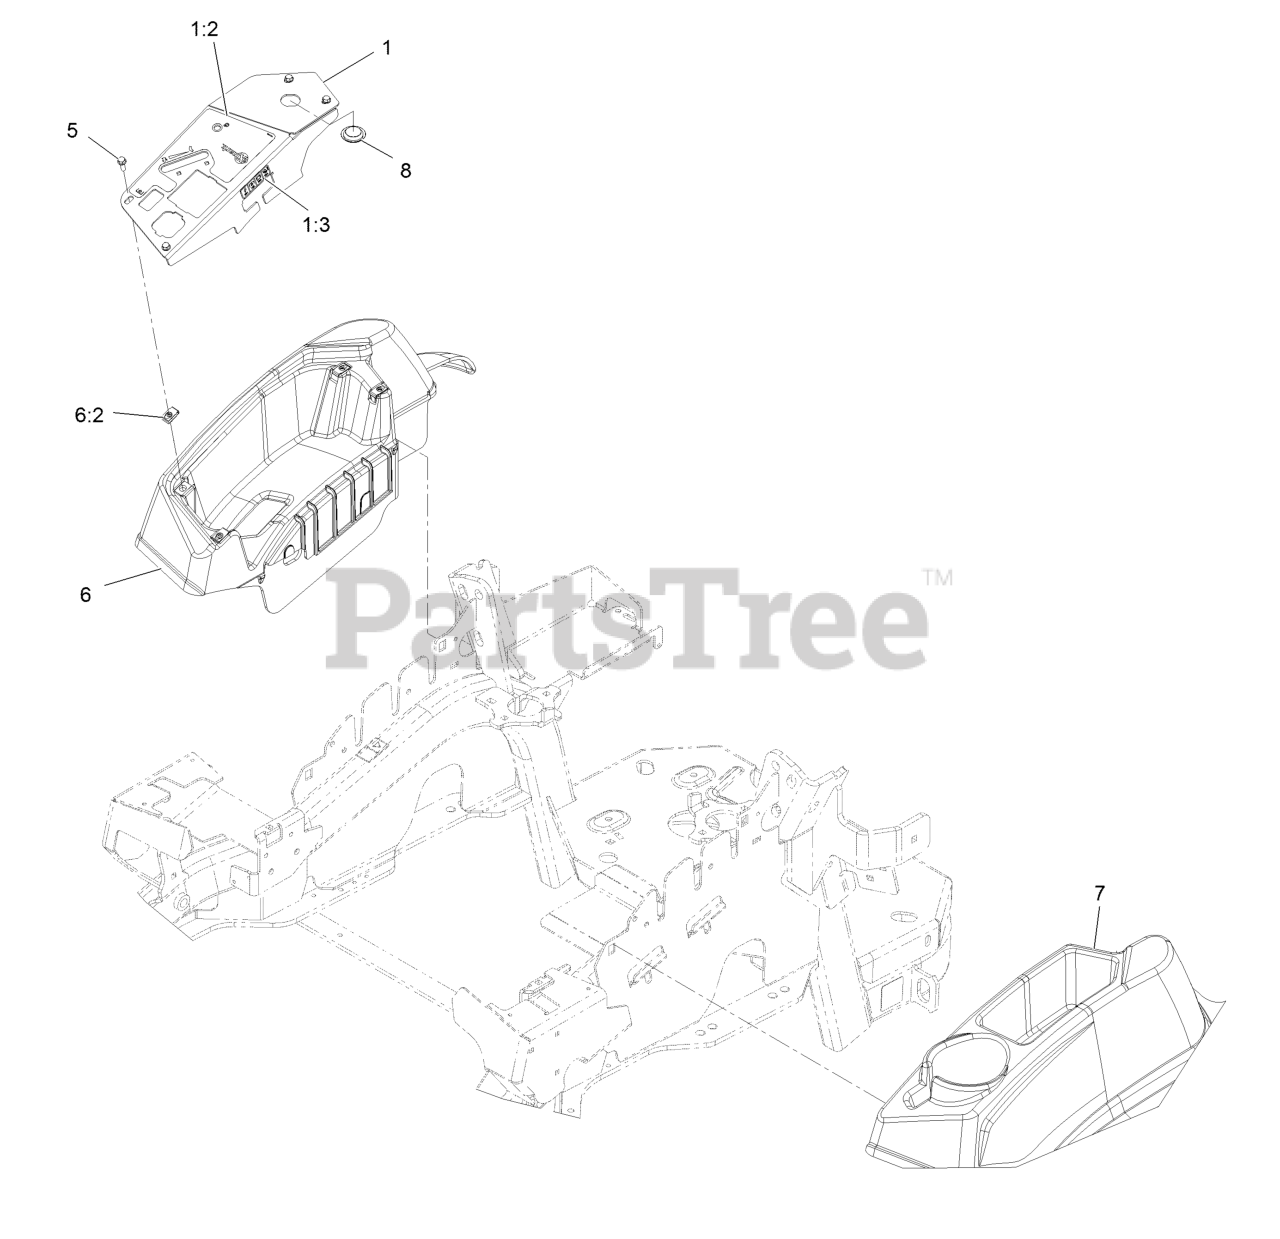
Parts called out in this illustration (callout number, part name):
1	ASM,Control Panel W/Decal
1:2	Decal-Control Panel Efi
1:3	Decal-Fuses
5	Screw-Machine 1/4-20 X 3/4
6	Console,RH As ASM
6:2	Nut-Retainer-Panel 1/4-20
7	Console, LH As
8	Plug-Plastic
